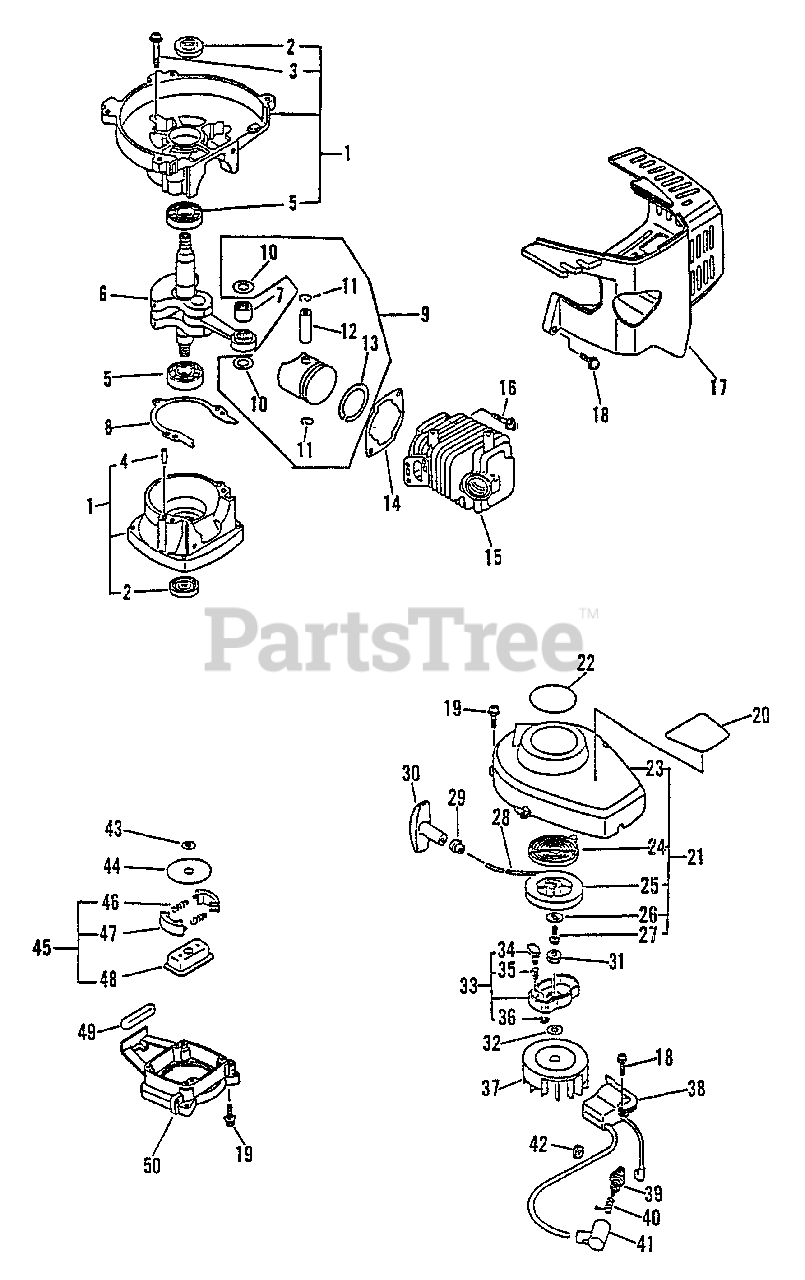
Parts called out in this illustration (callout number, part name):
1	CRANKCASE KIT
2	SEAL, OIL
3	SCREW - 5X28
4	PIN - LOCATING
5	BEARING, BALL - 6201
6	CRANKSHAFT ASSY
7	BEARING, NEEDLE
8	GASKET, CRANKCASE
9	PISTON KIT
10	SPACER, PISTON
11	RING, RETAINING
12	PIN, PISTON
13	RING, PISTON
14	GASKET, CYLINDER
15	CYLINDER
16	SCREW - 5X22
17	COVER, ENGINE
18	SCREW - 4X22
19	SCREW - 4X16
20	LABEL - MODEL LHS-3000
21	STARTER ASSY
22	LABEL - LESCO
23	CASE, STARTER
24	SPRING, REWIND
25	REEL, ROPE
26	WASHER
28	ROPE, STARTER - 3X890
29	GUIDE, ROPE
30	GRIP, STARTER
31	NUT - LEFT HAND
32	WASHER - 8
33	STARTER PAWL ASSY
34	PAWL, STARTER
35	SPRING, RETURN
36	RING, RETAINING - 4
37	FLYWHEEL
38	COIL, IGNITION
39	SPARK PLUG -- BPM-7A
40	TERMINAL, SPARK PLUG CAP
41	CAP, SPARK PLUG
43	WASHER, CLUTCH
44	PLATE, CLUTCH
45	CLUTCH ASSY
46	SPRING, CLUTCH
47	SHOE, CLUTCH
48	HUB, CLUTCH
49	CUSHION, FUEL TANK
50	CASE, CLUTCH
